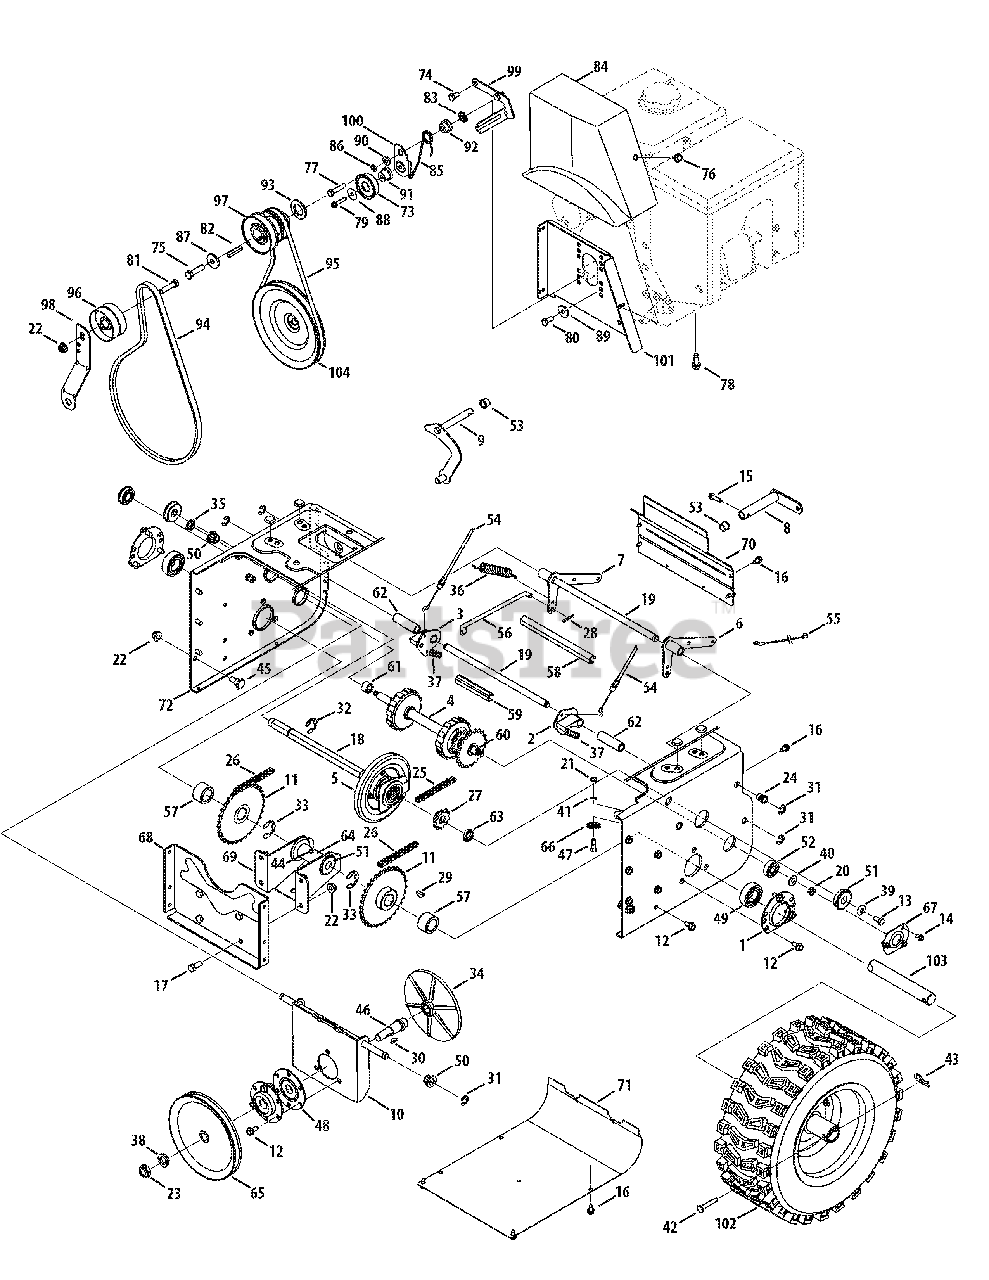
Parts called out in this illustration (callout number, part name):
1	Housing, Bearing
2	Dogg, Steering Drive, LH
3	Dogg, Steering Drive, RH
4	Shaft Assembly, Steering
5	Assembly, Friction Wheel
5	Wheel, Friction, Bonded
5	Screw, Hex Wash
6	Bracket, Auger Actuator
7	Bracket, Drive Actuator
9	Rod Assembly, Shift
10	Brkt, Friction Drive Suprt.
11	Sprocket, 32T
12	TT Screw, 5/16-18 x .750
13	Screw, Hex Cap Lock,
14	Screw, Hex, 1/4-20 x .50
15	Screw, Hex, 1/4-20 x 1.00
16	Screw, Hex Wash.
17	Screw, Hex Cap, 3/8-16
18	Shaft, Hex Drive
19	Shaft, Actuator
20	Nut, Hex Insert Jam Lock
21	Nut, Hex, 1/4-28 GR5
22	Nut, Hx Flnge Insert Lk
23	Nut, Hx Insert Jam Lk
24	Nut, Insert 3/8-16
25	Chain, Endless, #41 x 36L
26	Chain, #420 x 40L
27	Sprocket, #41 x 10T
28	Pin, Internal Cotter
29	Key, Woodruff
30	Key, Hi-Pro, 3/16 x 5/8
32	Ring, Retaining
33	Ring, Retainer
34	Plate, Drive
35	Speed Nut, .500
36	Spring, Extension
37	Spring, Extension
38	Washer, Lock, 5/8
39	Wsh, Bell., .34 x .872 x .06
40	Wash, .406 x .875 x .059
41	Washer, Lock, 1/4
42	Pin, Clevis
43	Pin, Internal Cotter
44	Fitting, Lube, 3/16 Drive
45	Screw, Shldr., .498 x .34
46	Spindle, Drive Plate
47	Screw, Hex Shldr., 1/4-28
48	Ass’y, Bearing/Housing
49	Bearing, Self Aligning
50	Bearing, Hex Flange
51	Bearing, Ball
52	Bush, Flg, .5625 ID x 1.375 x .4375
53	Bush, Flg, .5 ID x .627 OD
54	Cable, Steering
55	Cable, Auger Idler
56	Rod, Drive Clutch
57	Spacer, 1.01 x 1.50 x .93
58	Spacer, .49 x 7.865
59	Spacer, .49 x 3.545
60	Spacer, .566 x .87 x .190
61	Spacer, .566 x .87 x 1.25
62	Spcr., .514 x .632 x 2.44
63	Spacer, .675 x 1.0 x .23
64	Spcr, .6725 x 1.125 x 2.48
65	Pulley, Drive
66	Roller, Cable
67	Retainer Bracket
68	Bracket, Frame Support
69	Bracket, Axle Support
70	Cover, Upper Frame
71	Cover, Lower Frame
72	Trans Frame
73	Idler Pulley Assembly
74	Screw, Hex 5/16-24 x .75
75	Screw, Hex 3/8-24 x 1.25
76	Screw, Hx Wash Hd Tapp
77	Screw, Hex Cap, 5/16-24 x 1.50
78	Screw, 3/8-16 x 1.00
79	Screw, 1/4-20 x 1.25
80	Screw, Hex Cap, 5/16-24 x .875
81	Screw, Hex Cap, 3/8-16 x 1.75
82	Key, Square, 1/4 x 1.5
83	Nut, Push
84	Cover, Belt
85	Torsion Spring, .850 dia. x .333 lg.
86	Washer, Lock, 5/16
87	Washer, Flat, .406 x 1.25
88	Washer, Flat, .265 x 1.0 x .030
89	Spacer, Shoulder
90	Shldr. Spacer, .3175 x .500 x .094
91	Shldr. Spacer, .260 x .785 x .538
92	Shoulder Spacer, .340 x 1.00
93	Spacer, 1.02 x 1.63 x .1425
94	V-Belt, 4L x 44.60
95	V Belt, 3/8 x 36.68
96	Pulley, Flat Idler, 2.75 OD
97	Double Pulley, 3.25 x 2.75
98	Bracket, Auger Idler
99	Belt Keeper Bracket
100	Idler Drive Wheel Bracket
101	Belt Cover Bracket
102	Wheel Ass’y. - LH
102	Wheel Ass’y. - RH
103	Axle, Wheel, 45"
104	Auger Pulley, 10.0 x .5
